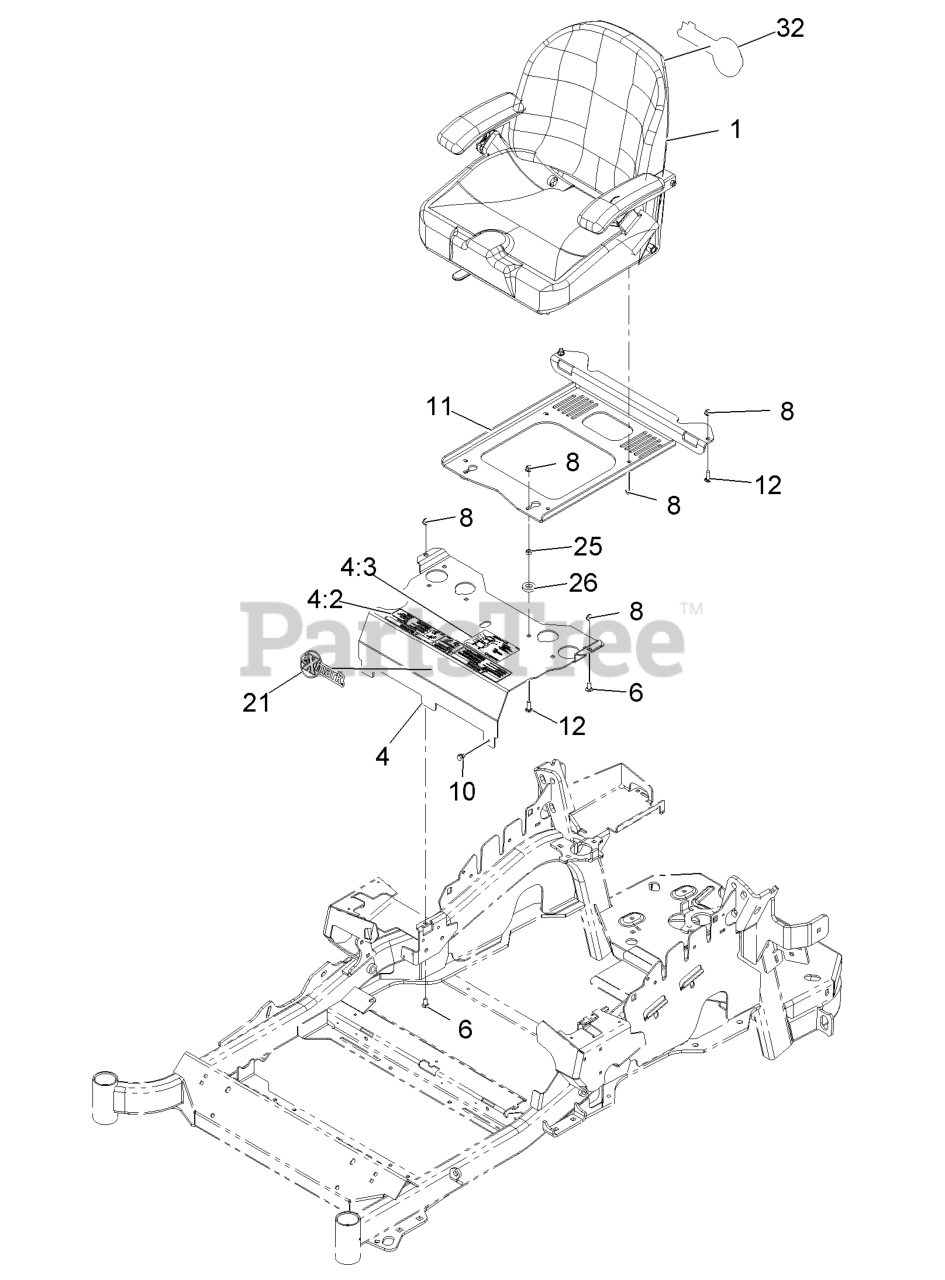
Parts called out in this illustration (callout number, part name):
4	MOUNT-SEAT
4:2	DECAL-CONSOLE
4:3	DECAL-SERVICE AID
6	SCREW-CARR
8	NUT-HF, NI
11	PLATE-SUPPORT, SEAT
12	SCREW-CARR
25	NUT-HEX
32	DECAL,EXMARK LOGO
